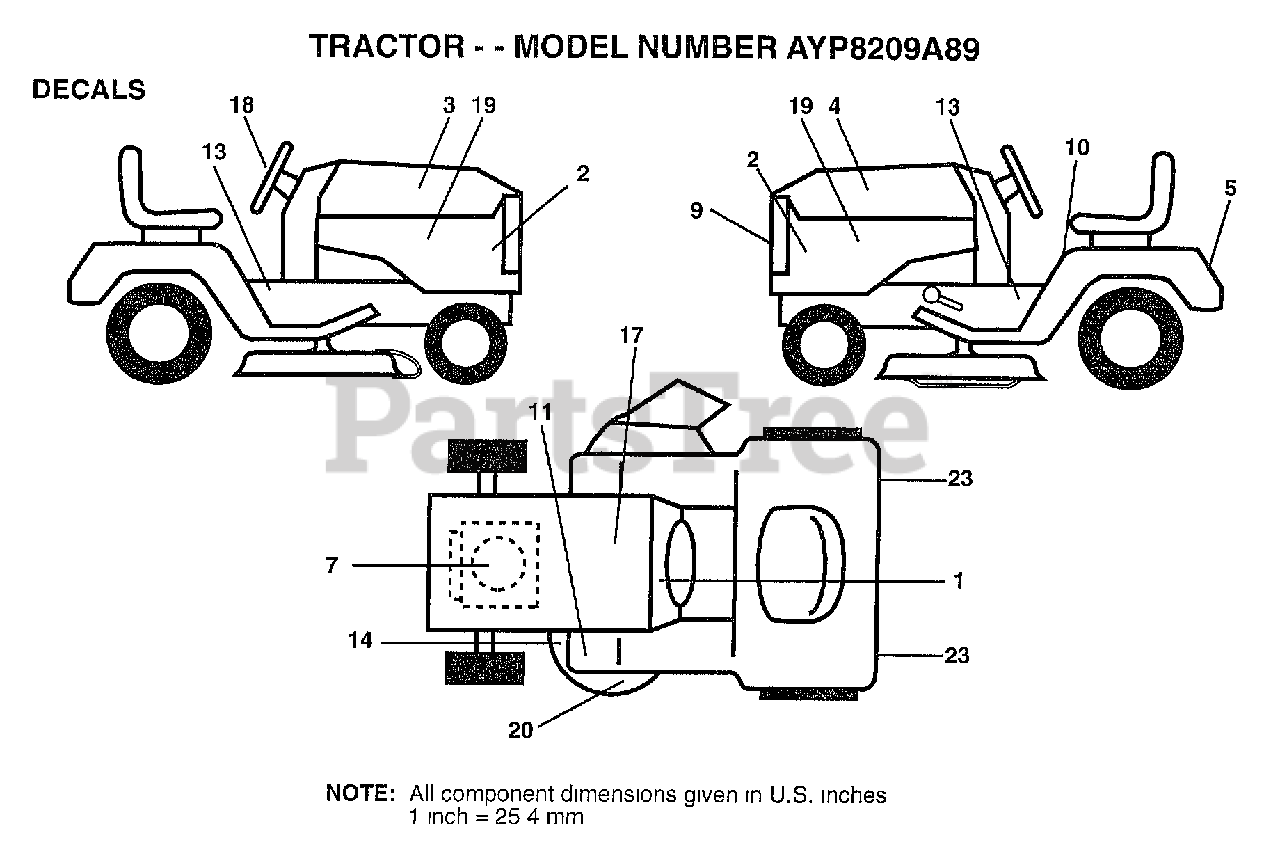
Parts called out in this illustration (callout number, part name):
1	"DECAL-OPER,GEAR D"
2	NAMEPLATE.HD.WIZA
3	DECAL.HD.RH.WIZRD
4	DECAL.HD.LH.WIZRD
6	DECAL.GRILLE.WIZ+
7	DECAL, ENGINE
9	DECAL.GRILLE.WIZ+
10	"DECAL DANGER,FEND"
13	"DCL.CHASSIS.50"""
17	DECAL.BATRY.3-3908
18	DECAL INS STG WHL
19	DECAL.PANEL.SIDE
20	DECAL DECK WIZ +
23	REFLECTOR-TAIL YT
